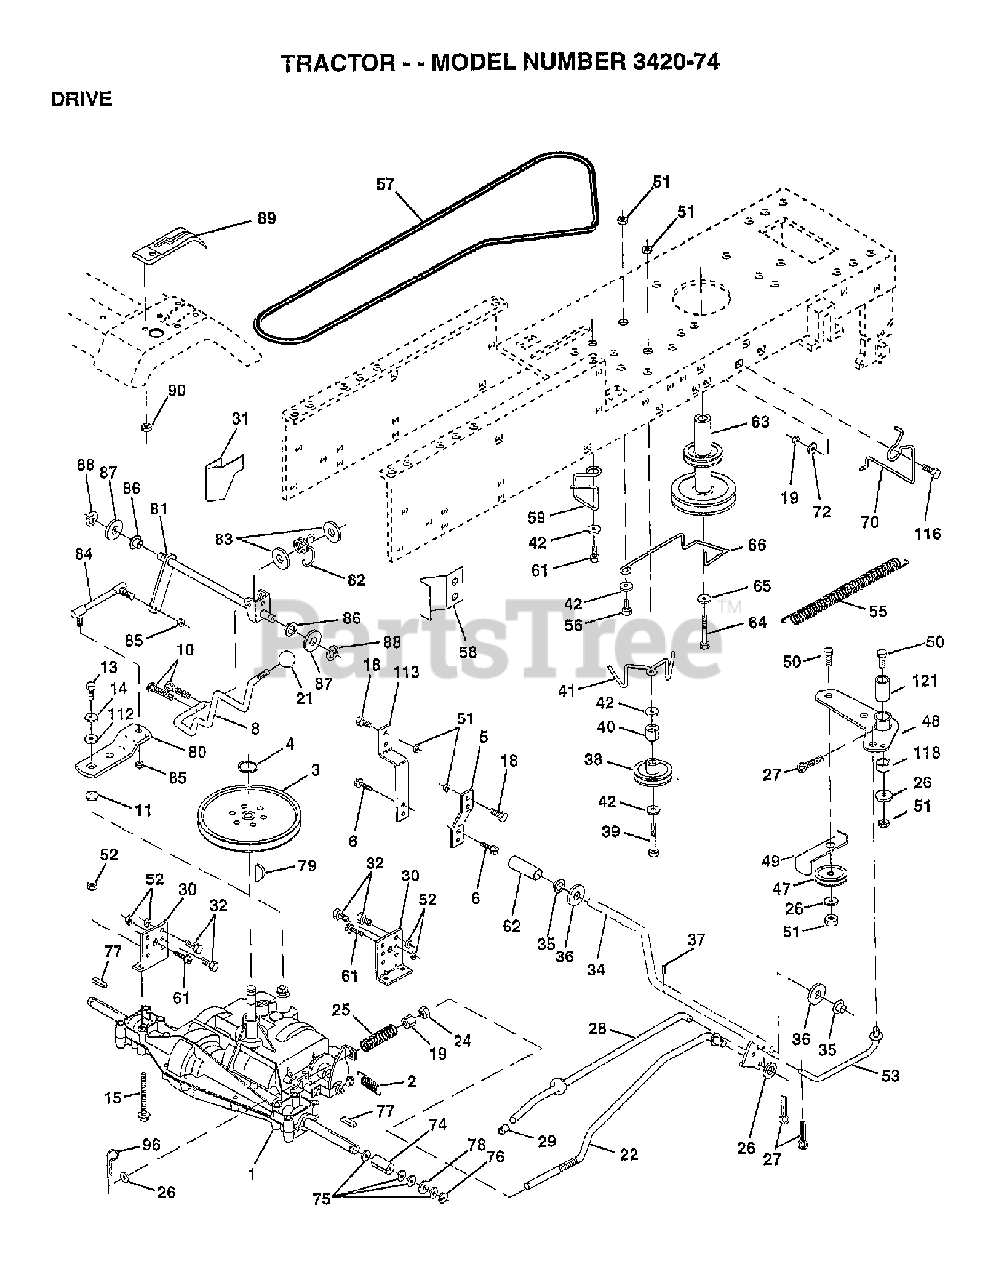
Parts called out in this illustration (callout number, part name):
2	SPRING T
3	PULLEY TRANS
4	RETAINING RING LT
5	STRAP TORQUE
6	Screw, Lt
8	ROD SHIFT
10	PIN COTTER
11	WASH-SHFT PLT LT
12	WASHER
14	LOCKWASHER
15	BOLT HEX 5/16-18 GR 5
19	NUT
21	KNOB T (1/2-HOLE)
22	ROD BRAKE
24	NUT
25	SPRING ROD LT
27	COTTER PIN
29	PLUNGER CAP
30	BRACKET TRANSAXLE
31	KEEPER BELT LH
32	BOLT
34	SHAFT, FOOT PEDAL
35	BEARING.NYLON
36	WASHER LT
37	Drive Pin, 3/16 X 1"
38	FLAT IDLER PULLEY
40	SPACER T
42	WASHER
47	Idler Pulley
48	BELLCRANK ASSEMBLY
49	RETAIN BELT
50	Hex Bolt
51	LOCKNUT
52	LOCKNUT
55	SPRING, RETURN LT
57	Ground Drive Belt, 95.25
62	PEDAL COVER
63	PULLEY ENGINE
65	LOCKWASHER
66	KEEPER BELT ENGINE
70	KEEPER BELT ENG
72	WASHER
74	SPACER AXLE
76	E-RING LT
77	SQUARE KEY
79	KEY.WOODRUFF
80	ARM SHIFT
81	SHAFT ASM CROSS 20"
82	SPRING,TORSION
83	WASHER
84	ROD TIE 20"
85	NUT LOCK CENTER 1/4 -28 FNTHD
86	BUSHING.STEERING.ROD
87	WASHER D
88	KLIP RING
90	NUT.PUSH.3/16
96	RETAINER M
112	WASHER LT
113	STRAP TORQUE LH LT
116	BOLT
121	NYLINER CLUTCHING
